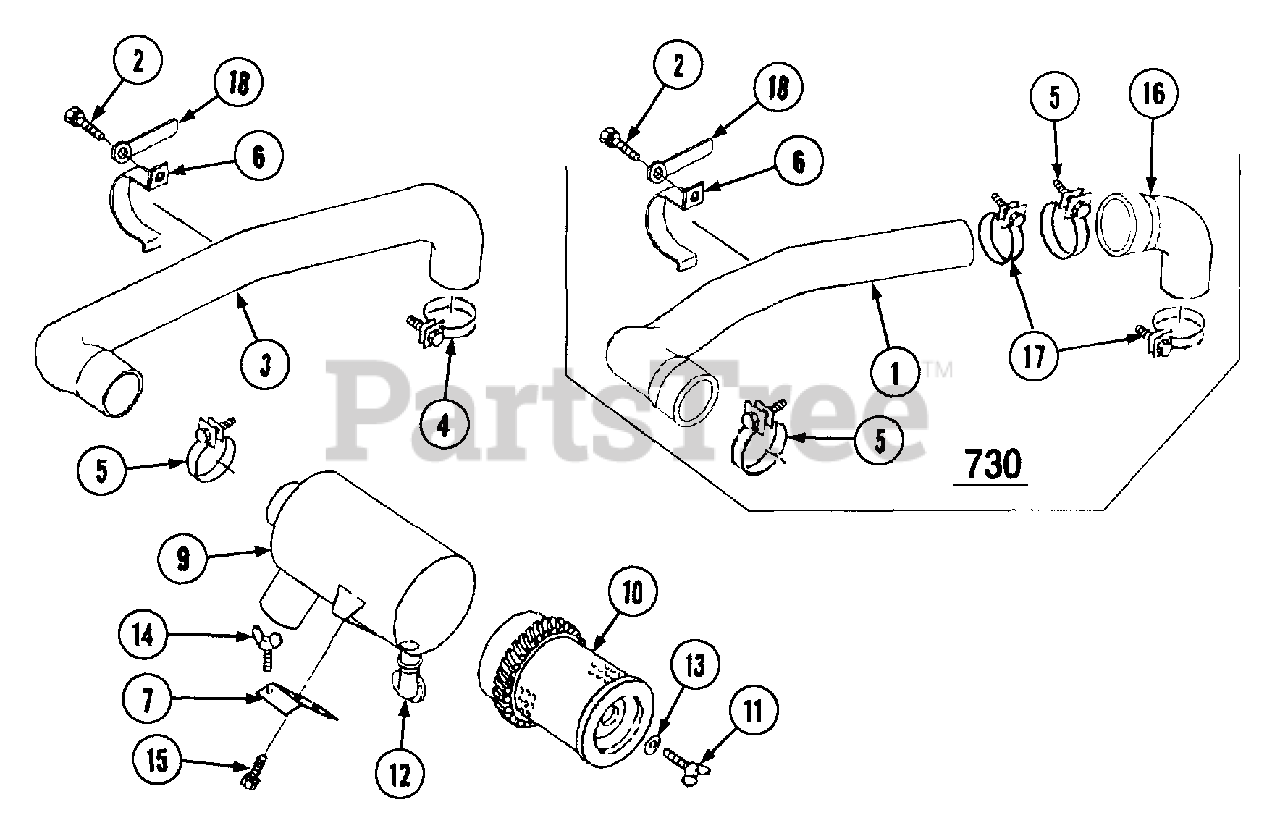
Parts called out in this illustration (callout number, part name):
1	Hose, Air A
11	Bolt Ass'y. Wing
16	Hose, Air B
17	Clamp, Hose
